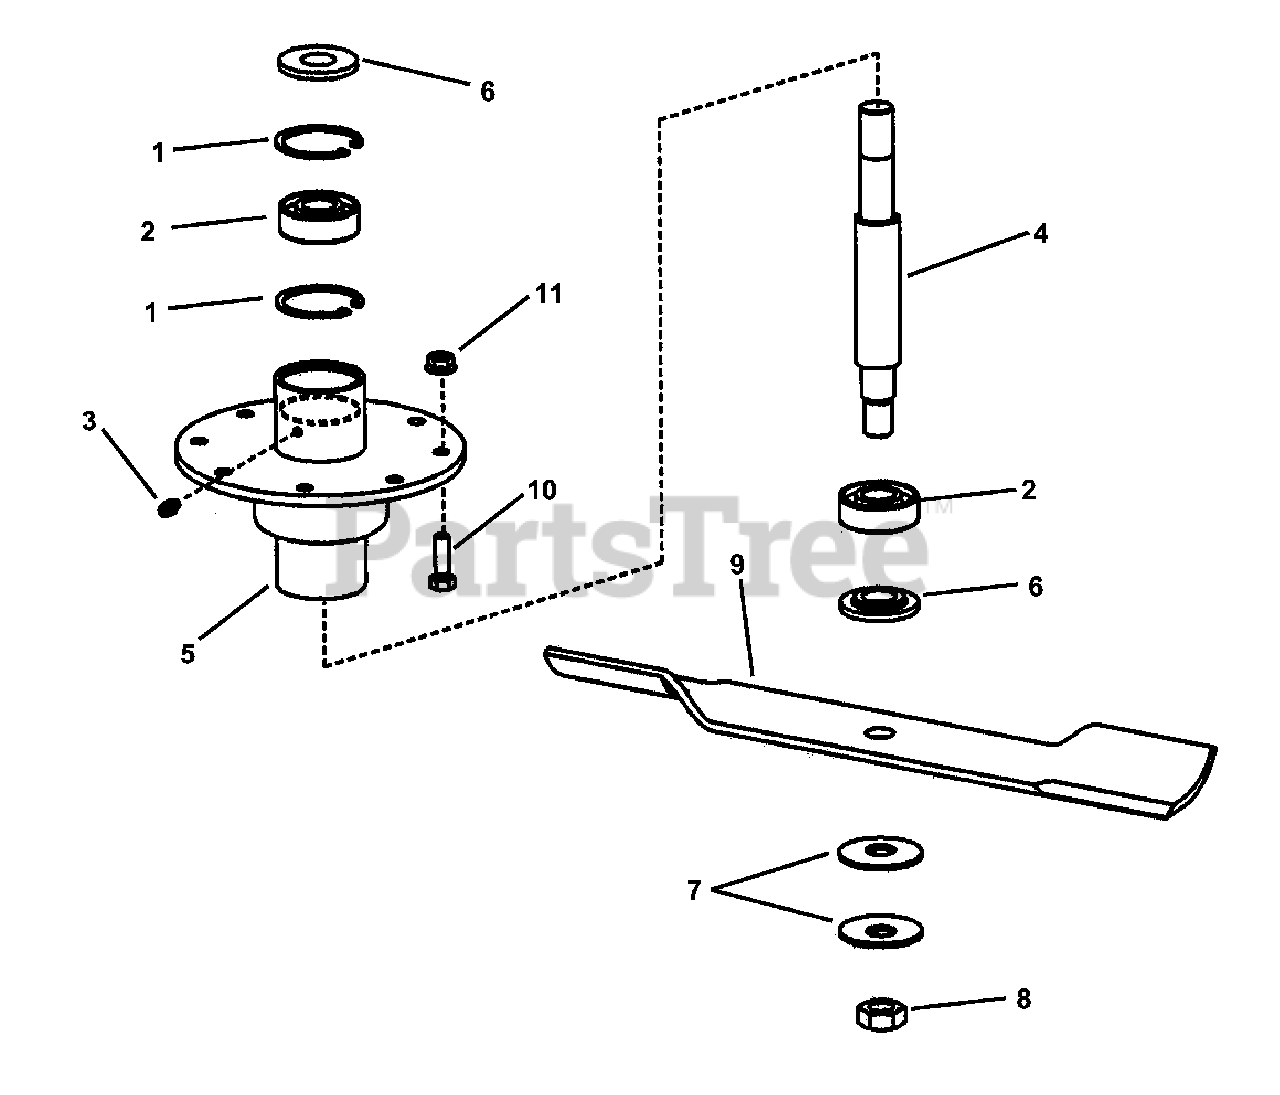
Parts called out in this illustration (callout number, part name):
1	RING, 1-3/4" Retaining
2	BEARING, Ball (3/4" I.D.)
3	FITTING, Lube (Press fit for .187 hole-no ball)
4	SHAFT, 48" Spindle (7.8" Long)
5	HOUSING, Spindle (weldment)
6	WASHER, Spindle
7	WASHER, Belleville
8	NUT, 5/8-18 Hex Jam
9	BLADE, 16-1/2" High Lift
10	SCREW, 5/16-18 x 1" Hex Head Cap, Grade 5
11	NUT, 5/16-18 Hex Flange Lock
